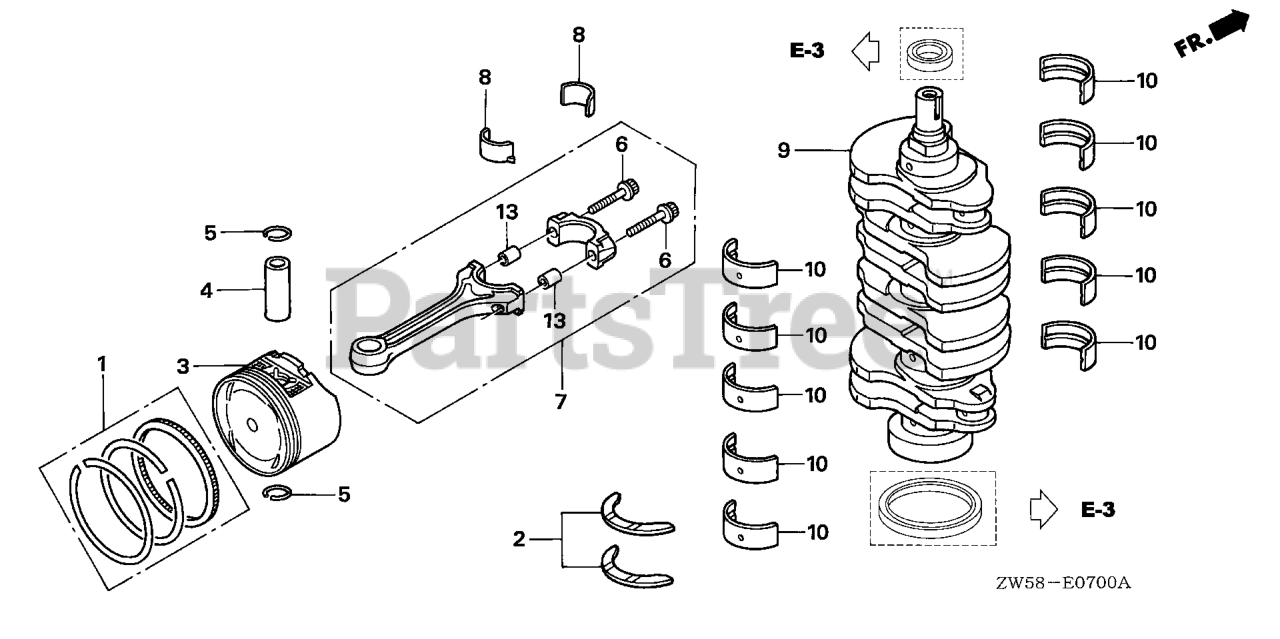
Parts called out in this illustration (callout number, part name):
1	RING SET, PISTON (STD)
2	WASHER SET, THRUST (DAIDO)
3	PISTON
4	PIN, PISTON
5	CLIP, PISTON PIN
6	BOLT, CONNECTING ROD
7	ROD, CONNECTING
8	BEARING A, CONNECTING ROD (BLUE) (DAIDO)
8	BEARING B, CONNECTING ROD (BLACK) (DAIDO)
8	BEARING C, CONNECTING ROD (BROWN) (DAIDO)
8	BEARING D, CONNECTING ROD (GREEN) (DAIDO)
8	BEARING E, CONNECTING ROD (YELLOW) (DAIDO)
8	BEARING F, CONNECTING ROD (PINK) (DAIDO)
8	BEARING G, CONNECTING ROD (RED) (DAIDO)
9	CRANKSHAFT
10	BEARING A, MAIN (BLUE) (TAIHO)
10	BEARING B, MAIN (BLACK) (TAIHO)
10	BEARING C, MAIN (BROWN) (TAIHO)
10	BEARING D, MAIN (GREEN) (TAIHO)
10	BEARING E, MAIN (YELLOW) (TAIHO)
10	BEARING F, MAIN (PINK) (TAIHO)
13	PIN, DOWEL (10X12)
